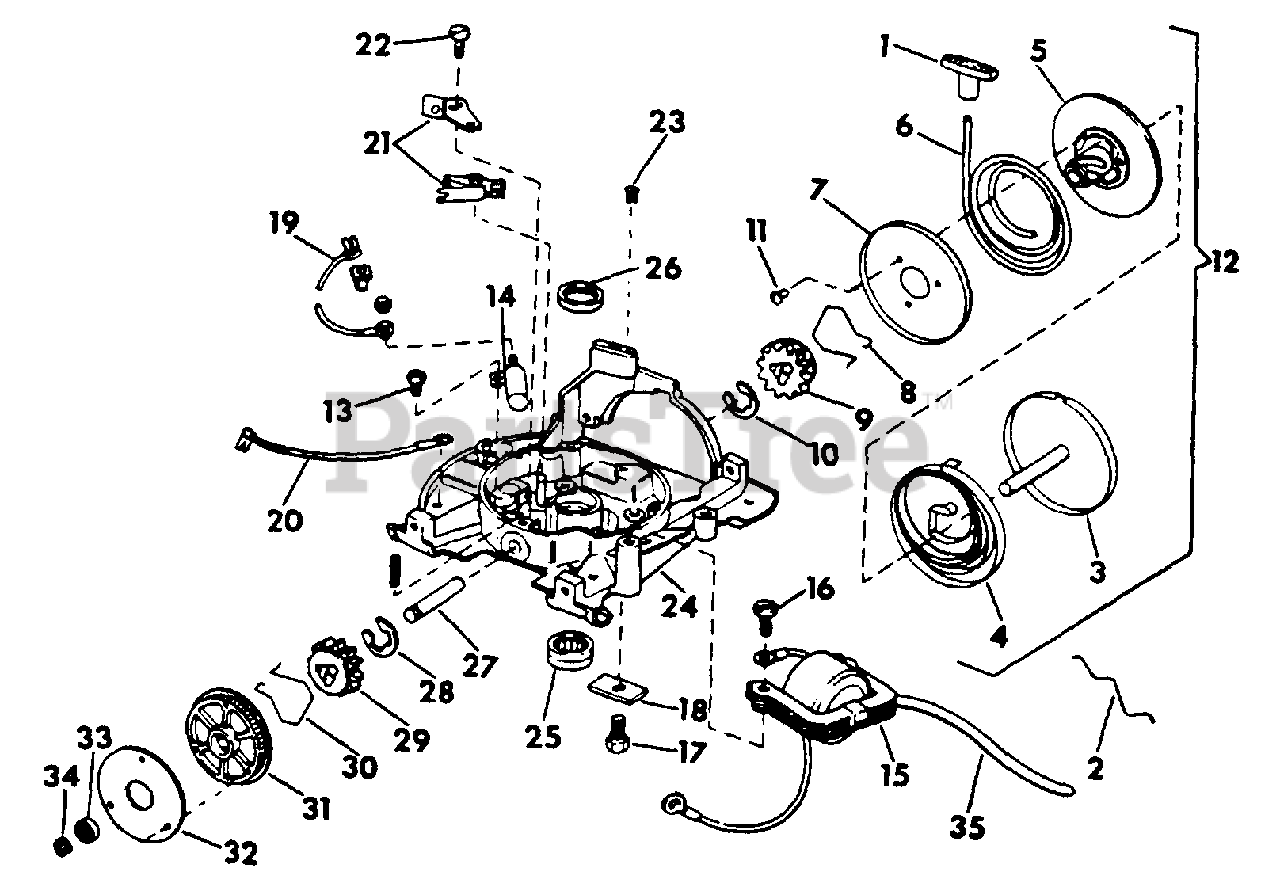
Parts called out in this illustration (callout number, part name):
1	HANDLE, STARTER
2	SPRING, STARTER ROPE RETAINER
3	SPRING, CUP & PIN
4	SPRING, STARTER
5	PULLEY, STARTER
6	ROPE, STARTER - 53 IN.
7	PLATE, STARTER PULLEY
8	SPRING, STARTER PINION
9	PINION, STARTER
10	RING, RETAINER
11	SCREW, THD CUTTING STARTER
12	STARTER ASSY
13	SCREW, CONDENSER MTG
14	CONDENSER & NUT ASSY
15	COIL & LAMINATION ASSY
16	SCREW, LAMINATION MTG
17	SCREW, STARTER ATT
18	CLAMP, STARTER PIN
19	TERMINAL & LEAD ASSY
20	TERMINAL & LEAD ASSY
21	BREAKER BASE & ARM
22	SCREW, BREAKER BASE
23	GROMMET, COVER MTG
24	ARMATURE PLATE BRG & SEAL ASSY
27	SHAFT, STARTER
28	RING, RETAINING
29	PINION, STARTER
30	SPRING, STARTER PINION
31	PULLEY, STARTER
32	PLATE, STARTER PULLEY
33	BEARING, STARTER PULLEY NEEDLE
34	RING, RETAINING STARTER SHAFT
35	HIGH TENSION LEAD ASSY
